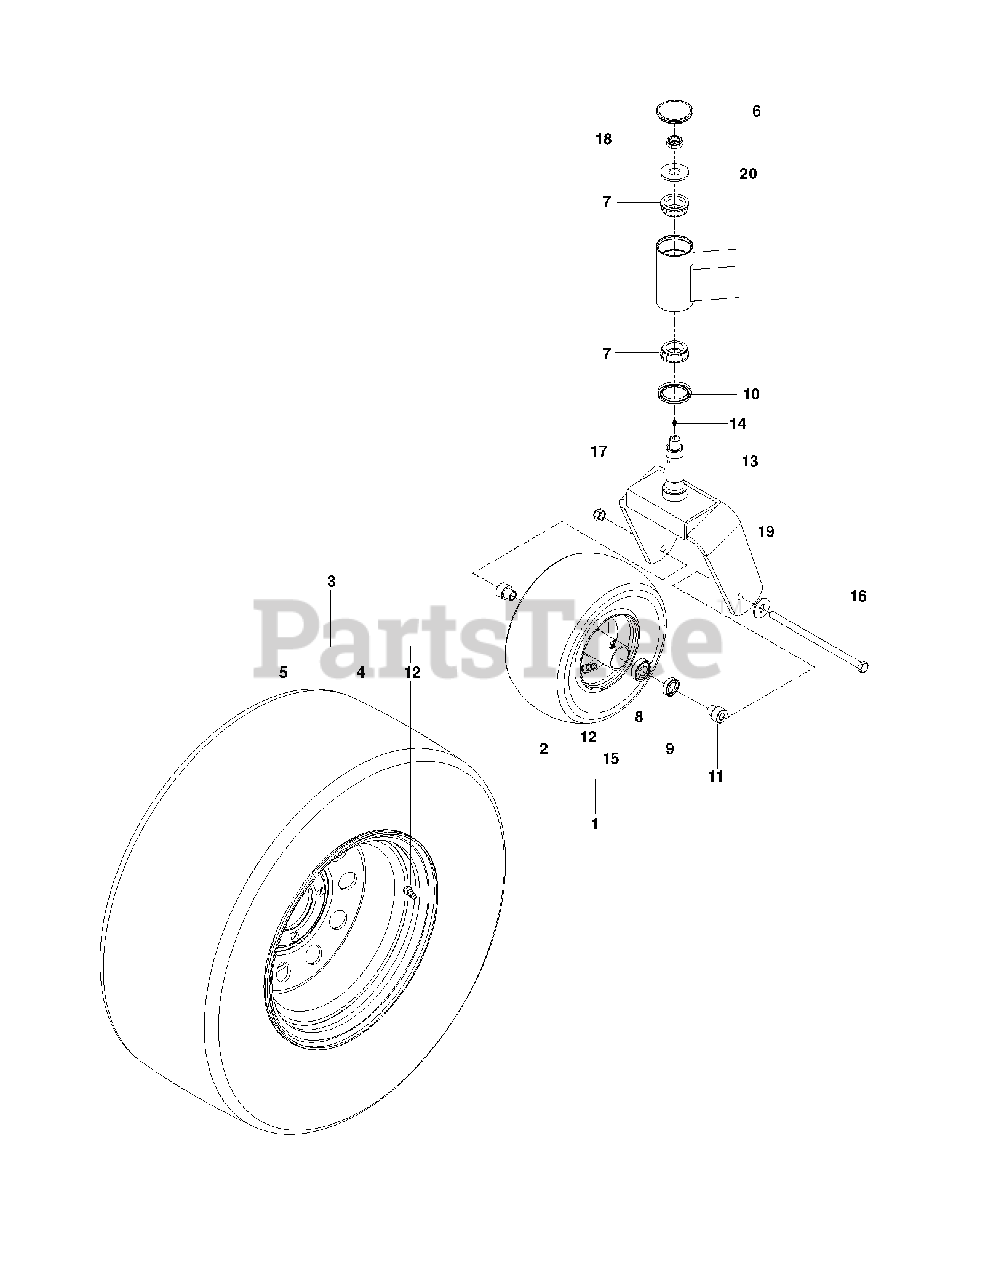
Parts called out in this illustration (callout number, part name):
1	FRONT TIRE ASSY
2	TIRE - SMOOTH 13X6.50-6
3	TIRE, 24 X 12-12
4	RIM, 12 X 8.5 W/1.75 NEG OS
5	REAR TIRE 24X12 TURFMASTER
6	CAP, DUST
7	BEARING, TAPPER ROLLER
8	TAPERED BEARING W/RACE
10	SEAL, BEARING
11	AXLE SPACER
12	VALVE STEM TR-412
15	ZERK
16	HEX SCREW 1/2-13 X 9.5 GR5
17	NUT, 1/2-13 HEX FLG NYLOC ZD
18	NUT, 3/4-16 HEX THIN NYLOC ZD
19	WASHER 1/2" FLAT
20	WASHER, 3/4 HARDENED
